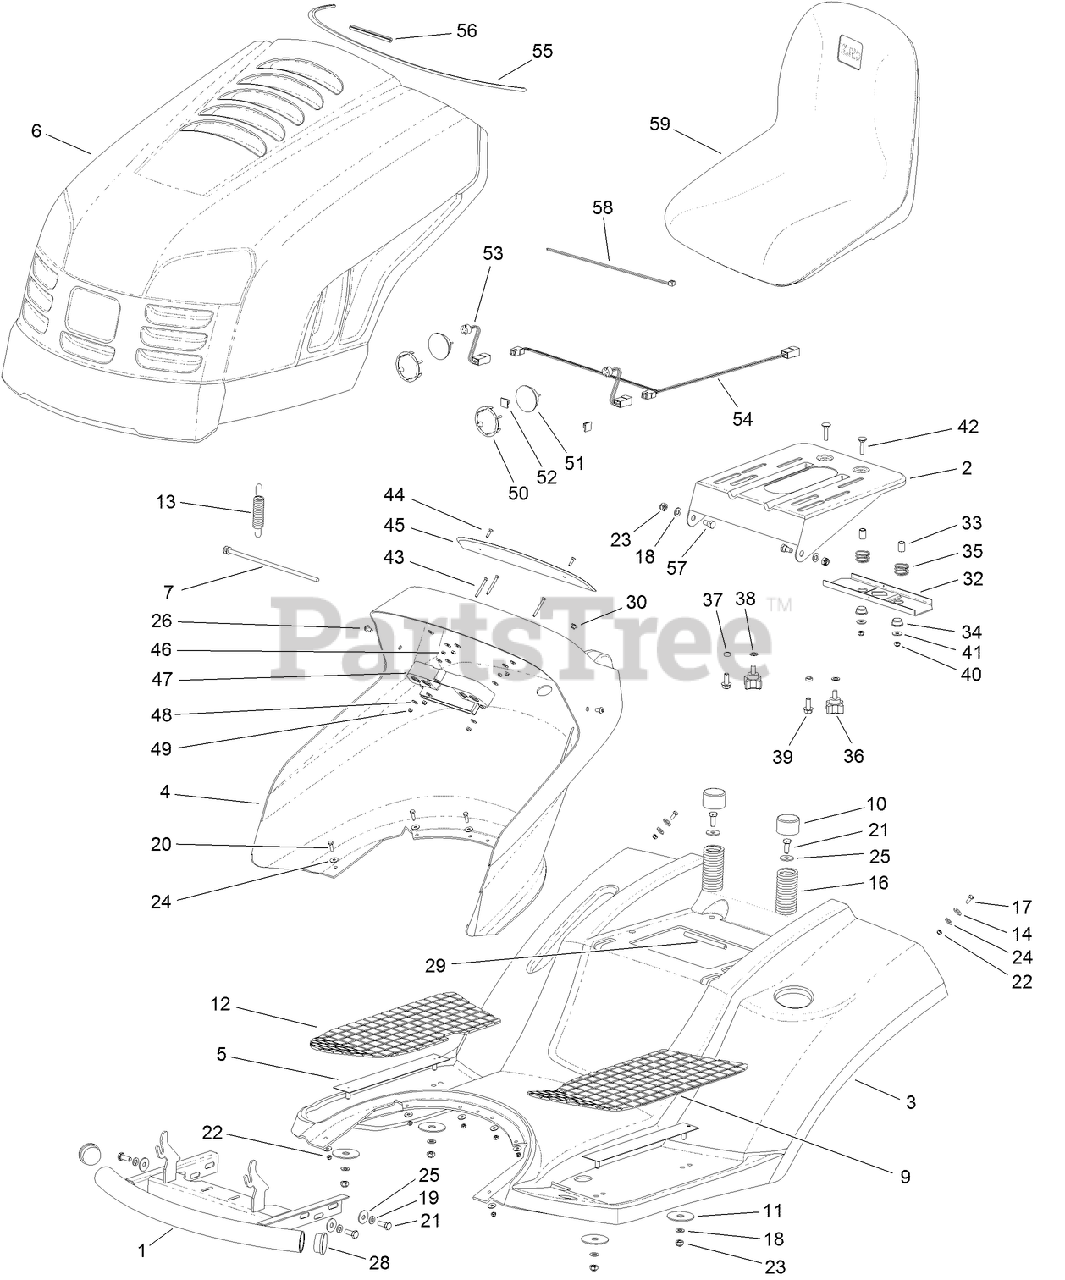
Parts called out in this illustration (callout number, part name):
1	BUMPER
2	BRACKET-SUPPORT, SEAT
3	FENDER-REAR
4	PANEL-DASH
5	HOLDER
6	HOOD ASM
7	HOLDER-SPRING
9	MAT-FOOT, LH
10	CAP-HUB
11	WASHER-RUBBER
12	MAT-FOOT, RH
13	SPRING-HOOD
14	WASHER-RUBBER
16	SPRING-SEAT
18	WASHER-PLAIN
19	WASHER-SPRING
21	SCREW-HH
22	NUT-LOCK
23	NUT-LOCK, NI
24	WASHER-FLAT
25	WASHER-PLAIN
26	SCREW-HH
29	TRIM-RUBBER
32	BRACKET
33	SPACER-SPLIT
34	BUSHING
35	SEAT-SPRING
36	KNOB-ADJUST
37	SPACER
38	WASHER-SPRING
39	SCREW-SUPPORT, SEAT
40	NUT-LOCK
41	WASHER-FLAT
42	SCREW-CARR
45	LENS-DASH
47	HOUSING-LIGHT, INDICATOR
48	WASHER
49	NUT-HEX
50	SOCKET-LAMP
51	BULB-LIGHT
52	CLIP-NYLON
53	HARNESS-WIRING, LIGHT BULB
54	HARNESS-WIRING, LIGHT
55	TRIM-RUBBER, HOOD
56	GASKET-FOAM
57	SCREW-SUPPORT, SEAT
58	TIE-CABLE
59	SEAT ASM
